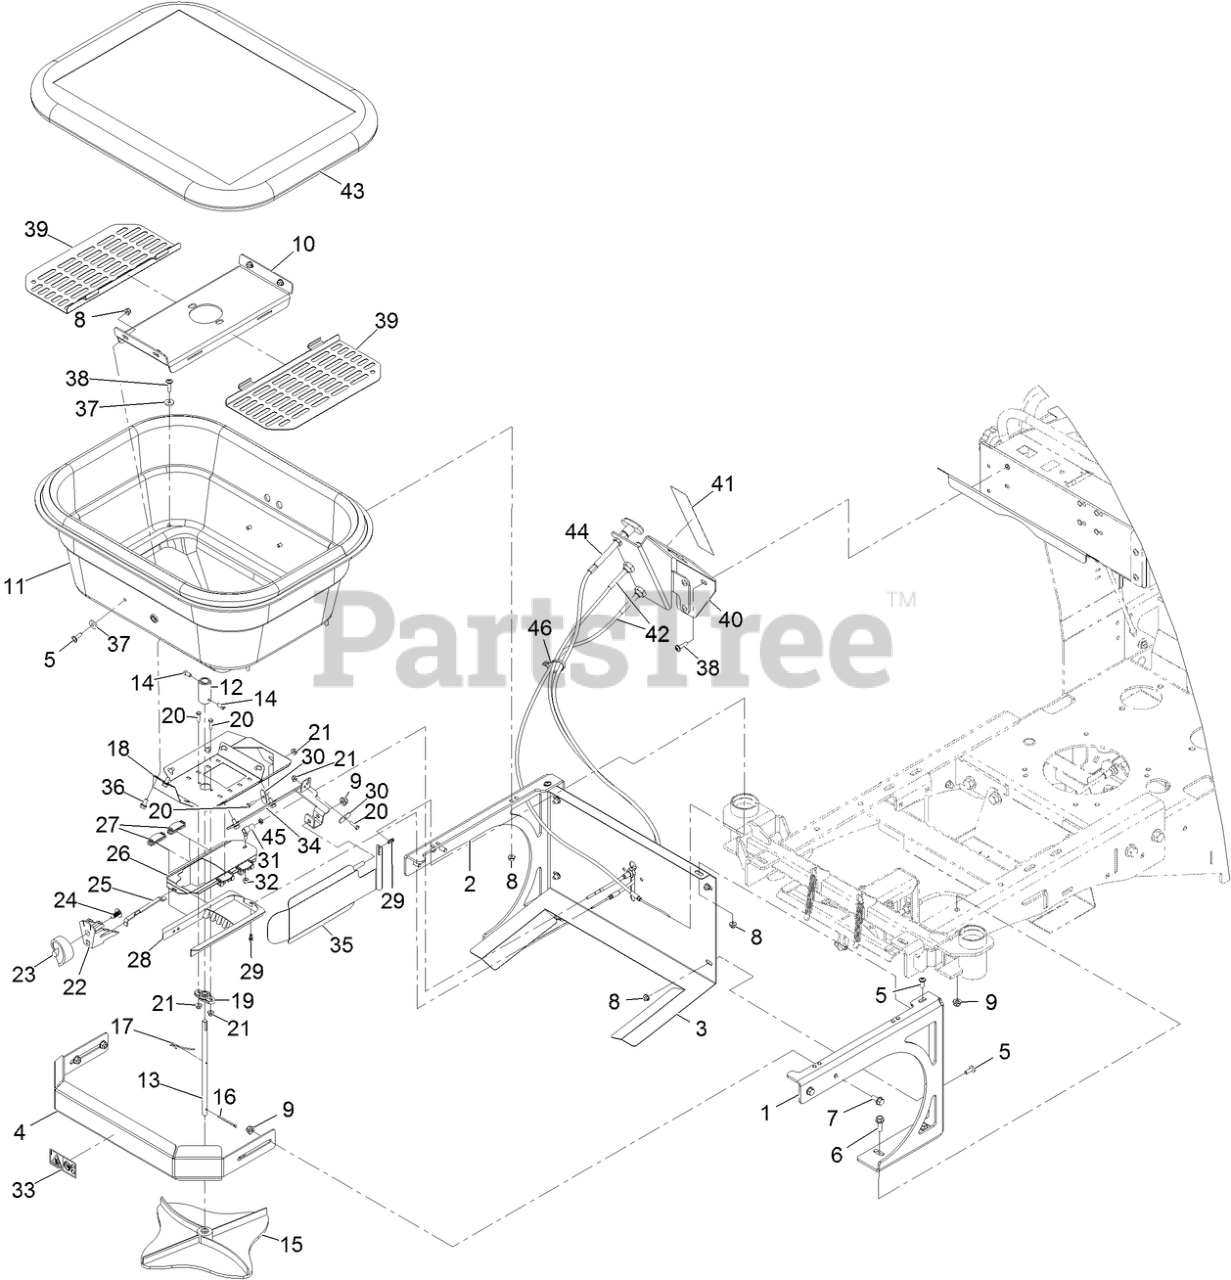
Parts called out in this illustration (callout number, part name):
1	WLD, FRAME, HOPPER, L, 120
2	WLD, FRAME, HOPPER, R, 120
3	BACKSHIELD, HOPPER, JR36
4	BUMPER, FRONT, HOPPER, 120
5	SCREW-HSBHF
6	SCREW-HHF
7	SCREW-HHF
8	NUT-HEX FLANGE
9	NUT-HEX FLANGE
10	PAN-HOPPER, 120
11	HOPPER-120LB
12	COUPLER-SS
13	SHAFT-HOPPER, 120
14	SCREW-SQH
15	SPINNER-SPREADER
16	PIN-COTTER
17	WIRE-AGITATOR
18	BASE-HOPPER, 120
19	BEARING-FLANGE
20	SCREW-HH
21	NUT-HEX FLANGE
22	MOUNT-DIAL
23	DIAL
24	CLIP
25	LINKAGE-GATE, RATE
26	SLIDE-DOOR, HOPPER
27	GUIDE-RATE, GATE
28	DIFFUSER
29	RETAINER-CABLE, WIRE
30	RETAINER, CABLE
31	BALL JOINT-SS
32	NUT-NYL LOCK,#10-32,ST/ST 18-8
33	DECAL-DISMEMBERMENT HAZARD
34	MOUNT-DEFLECTOR, SIDE
35	DEFLECTOR-SIDE, SPREADER
36	SCREW-HHF
37	WASHER
38	SCREW-HSBHF
39	SCREEN-HOPPER, 120
40	MOUNT-SPEEDOMETER
41	DECAL-HOPPER CONTROL
42	CABLE-PUSH/PULL
43	COVER-HOPPER, SMALL
44	120LB HOPPER CABLE
45	NUT-HEX, JAM
46	TIE-CABLE
